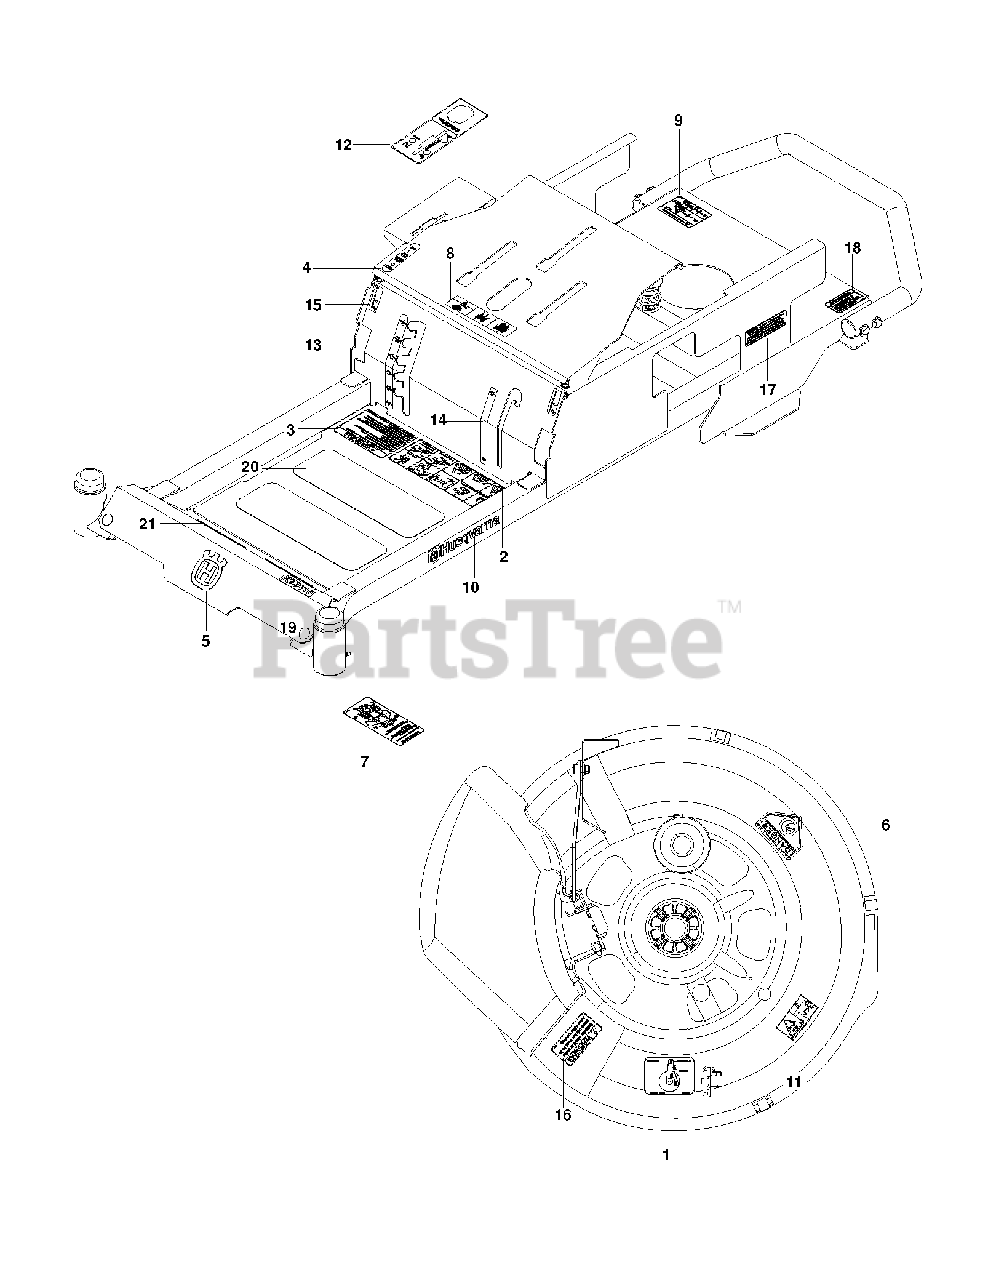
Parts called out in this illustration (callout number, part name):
1	DECAL, BELT ROUTING
2	DECAL, SAFETY WARNING
3	DECAL, WARNING
4	DECAL, PARK BRAKE
5	DECAL.AUGER.HUSQ.CROWN.SNOW
6	DECAL, CPSC
7	DECAL, SERVICE
8	EURO DECAL-BATTERY WARNIN6
9	DECAL, DO NOT TOW
10	RP.DECAL.BADGE.170MM.TEXTLOGO
11	DECAL, EURO SEVERING
12	DECAL, CONTROL PANEL HUS
13	DECAL, DECK HEIGHT
14	DECAL, BLADE ENGAGEMENT
15	DECAL, MOTION CONTROL
16	DECAL, CAUTION
17	DECAL, WARNING SPARK ARRESTOR
18	DECAL, PROP. 65
19	DECAL, RZ3016
20	ANTI-SKID PAD
